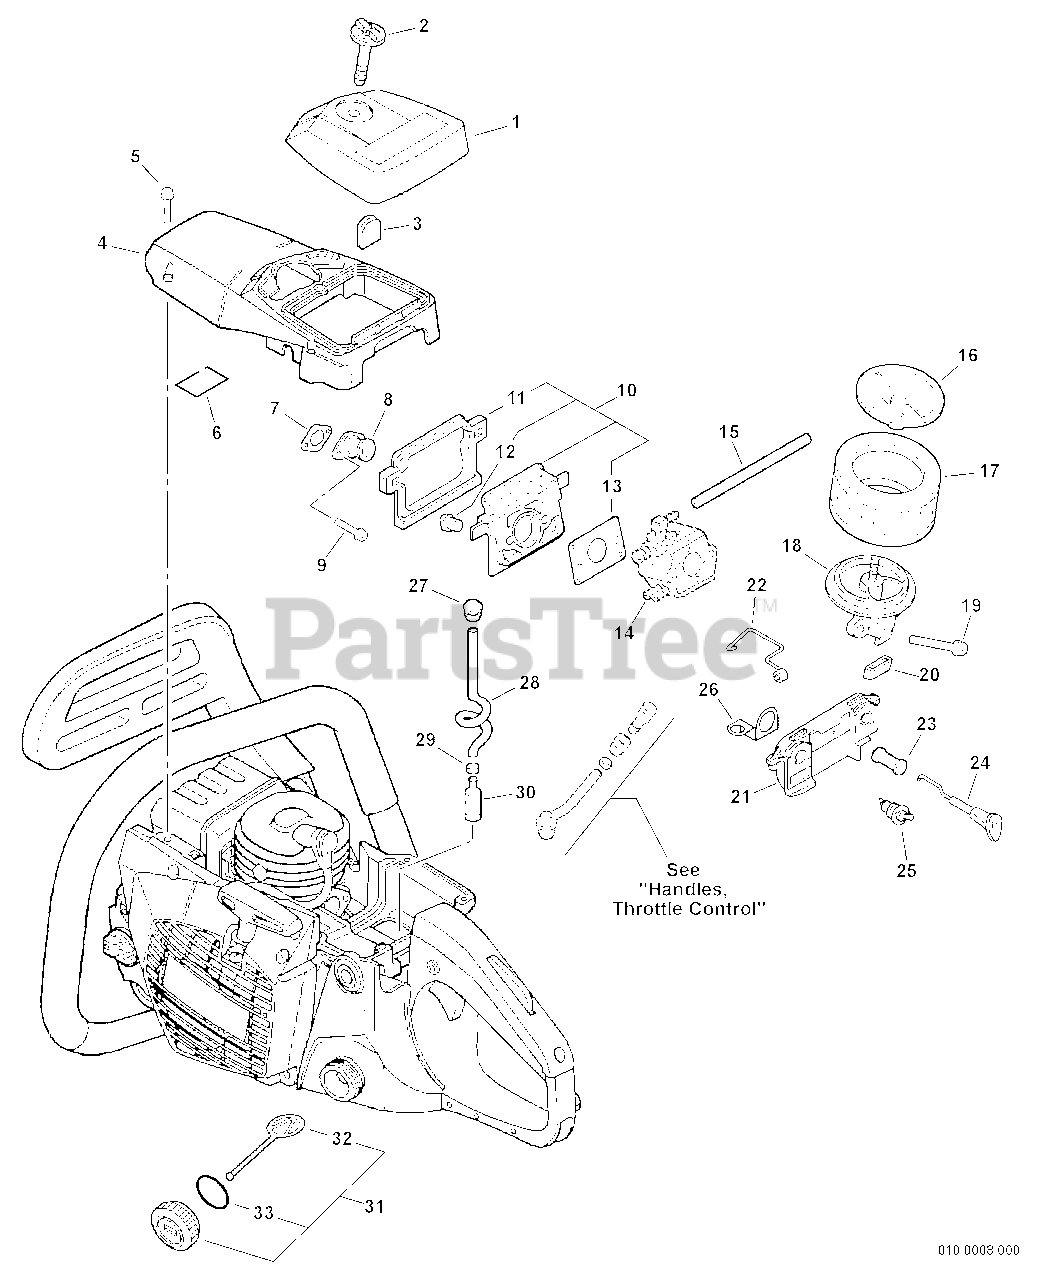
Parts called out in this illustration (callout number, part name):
1	COVER ASSY, AIR FILTER
2	THUMBSCREW
4	COVER, ENGINE
6	SHIELD, HEAT
7	GASKET, INTAKE
8	ADAPTOR, INTAKE
9	SCREW 5×12
10	INSULATOR KIT, INTAKE
11	CUSHION
13	GASKET, INTAKE
14	CARBURETOR
15	PIPE, IMPULSE 3×5×110
16	CAP, AIR FILTER
17	FILTER, AIR
18	MOUNT, AIR FILTER
19	BOLT 5×50
21	BRACKET, SWITCH
22	ROD, THROTTLE
23	GROMMET, CHOKE
24	ROD, CHOKE
25	SWITCH, ON-OFF
26	TERMINAL, SWITCH
28	PIPE, FUEL 3×6×165
29	CLIP Ø6.5 MM
30	FILTER, FUEL
31	CAP ASSY, FUEL
32	CONNECTOR, CAP L= 60 MM
33	O-RING 22
